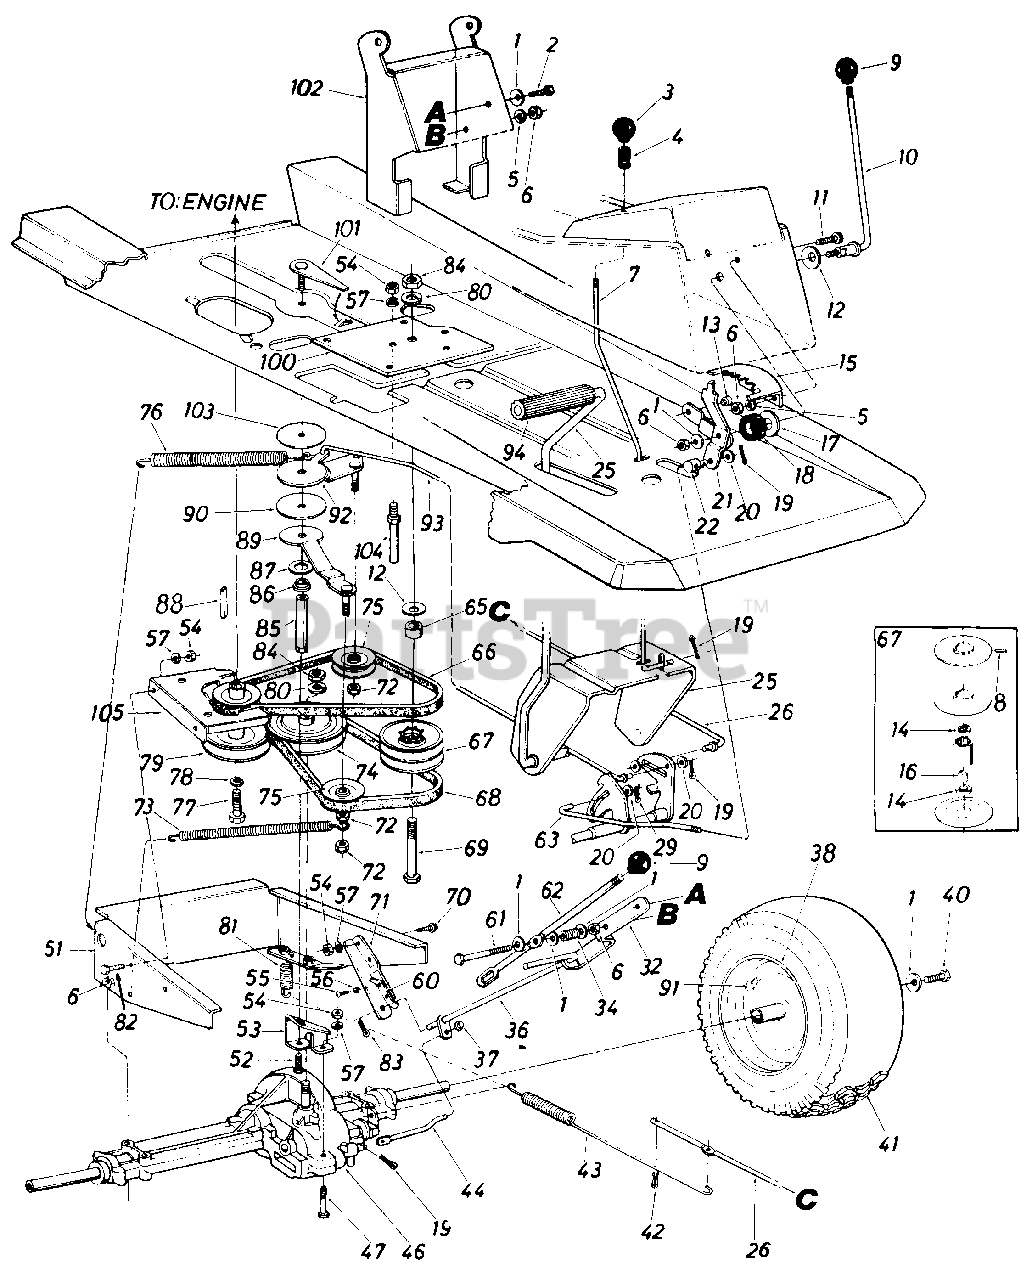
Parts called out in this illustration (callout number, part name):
1	Bell-Wash. .345" I.D. x .88" O.D.
2	Hex Wash. Hd. AB-Tap Scr. 1/4 x .62" Lg.
3	Ball Knob
4	Compression Spring
5	L-Wash. 5/16" I.D.
6	Hex Nut 5/16-18 Thd.
7	Brake Locking Rod
8	Spring Pin Spir. 5132" Dia. x .62" Lg.
9	Gear Shift Knob
10	Speed Control Lever
11	Truss Mach. Scr. 5/16-18 x .75" Lg.
12	Bell-Wash. .505" I.D. x 1.00"
14	Ball Brg. .50" I.D. x 1.38"
15	Index Bracket
16	Spacer.50" I.D. x .69" O.D. x 1.38" Lg.
17	Fl-Wash. 1/2" I.D. x 1.50"
18	Rubber Wash. .50" I.D. x 1.25" O.D.
19	Cotter Pin 1/8 x 1.00" Lg.
20	Fl-Wash. .344" I.D. x .688"
21	Speed Control Lever Brk't. Ass 'y.
22	Ferrule Engagement
25	Clutch-Brake Pedal Ass'y.
26	Brake Rod
29	Intern. Cotter Pin 5/16" Dia.
32	Shift Lever Brk't.
34	Spring
36	Shift Lever Ass'y.
37	Cap Speed Nut 1/4" Rod
38	Rear Wheel Rim Only
40	Hex L-Bolt 5/16-24 x .75" Lg.
41	Rear Wheel Ass'y. Comp.
42	Cot-Pin 118" Dia. x 1.25
43	Ext. Spring .75" O.D. x 17.0' Lg.
44	Shift Rod
46	Transaxle Comp.
47	Hex Bolt 1/4-20 x 1.75" Lg.
53	Torque Rod Bracket
54	Hex Nut 1/4-20 Thd.
55	C-Sink AB S-Tap Scr. #8 x .50"
56	Push-ln Nut #10
57	L-Wash. 1/4" I.D.
60	Spring Switch
61	Hex Bolt 5/16-18 x 2.25" Lg.
62	Upper Shift Lever
63	Speed Control Rod
65	Spacer.501" I.D. x .750" O.D. x .775
66	V"-Belt 5/8" L x 35" Lg.
67	Variable Speed Pulley Ass'y.
68	V"-Belt 5/8" L x 38" Lg.
69	Hex Bolt 1/2-13 x 4.0" Lg.
70	Hex Bolt 1/4-20 x .62" Lg.
71	Shift Lever Support
72	Hex Ins. L-Nut 3/8-24 Thd.
73	Extension Spring
74	5/8" V-Pulley 6.0" O.D.
75	"V"-Belt Idler 3.06" O.D.
76	Extension Spring .99" O.D. x 8.0" Lg.
77	Hex Bolt 7/16-20 x 1.0" Lg.
78	L-Wash. 7/16" I.D.
79	Engine Pulley
80	L-Wash. 1/2" I.D.
81	Brake Return Ext. Spring
82	Hex Bolt 1/4-20 x .75" Lg.
83	Cotter Pin 3132" Dia. x .75" Lg.
84	Hex Nut 1/2-13 Thd.
85	Torque Rod 3.835" Lg.
86	Flange Bearing .378
87	Fl-Wash. .640" I.D. x 1.24"
88	Sq. Key 1/4" x 2.00" Lg.
89	Idler Bracket Ass'y.
90	Thrust Wash. .635" I.D. x 3.50" O.D.
91	Air Valve
92	Idler Bracket Ass'y.
93	Clutch Rod
94	Foot Pad
100	Mounting Bracket Variable Speed Pulley
103	Thrust Wash. .385" I.D. x 3.50" O.D.
104	Belt Guard Pin 1/4" Dia. x 1.68" Lg.
105	Upper Engine Belt Guard
